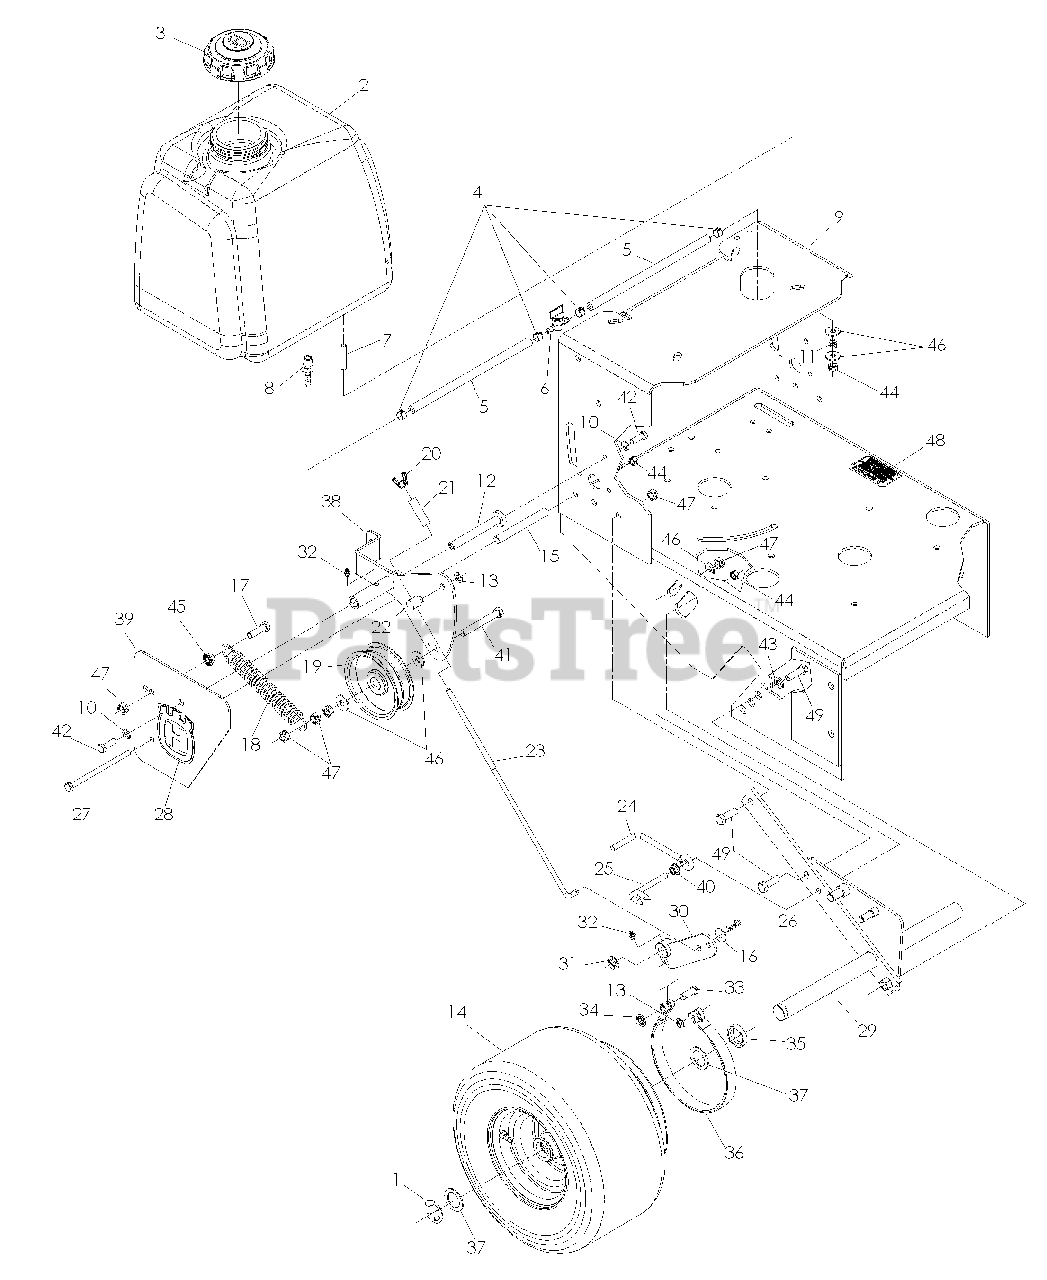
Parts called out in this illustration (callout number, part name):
1	E-RING 1"
3	GAS CAP
4	HOSE CLAMP
5	GAS LINE 10"
6	FUEL VALVE
9	REAR DECK W/DECALS
10	LOCKWASHER 5/16
12	SHOULDER PIVOT TUBE
13	RING, RETAINER
14	WHEEL ASSEMBLY W/DRUM, & PULLEYS
15	LONG SPACER
16	WASHER 5/16
17	HCS 3/8 -16 x 1 1/4
19	IDLER PULLEY
20	WINGNUT 5/16 NYLOC
24	BELT GUIDE
26	HAIRPIN #2
27	HCS 5/16 -18 x 5
28	DECAL, CROWN
29	AXLE WELDMENT
30	BRAKE ARM, RT
31	E-RING 1/2"
32	ZERK
33	CLEVIS PIN
34	BOLT RET. 3/8
36	BRAKE BAND
38	IDLER ARM, RT
38	IDLER ARM, LT
40	HFLN 5/16 -18
41	TAP BOLT 3/8-16 x 3
42	HCS 5/16-18 x 1
43	LOCK WASHER 3/8
44	NUT 5/16 -18 LOCK
45	HFLN 3/8-16
46	WASHER 3/8
47	NUT 3/8-16 LOCK
48	DECAL, PROP 65
49	HCS 3/8 -16 x 1
